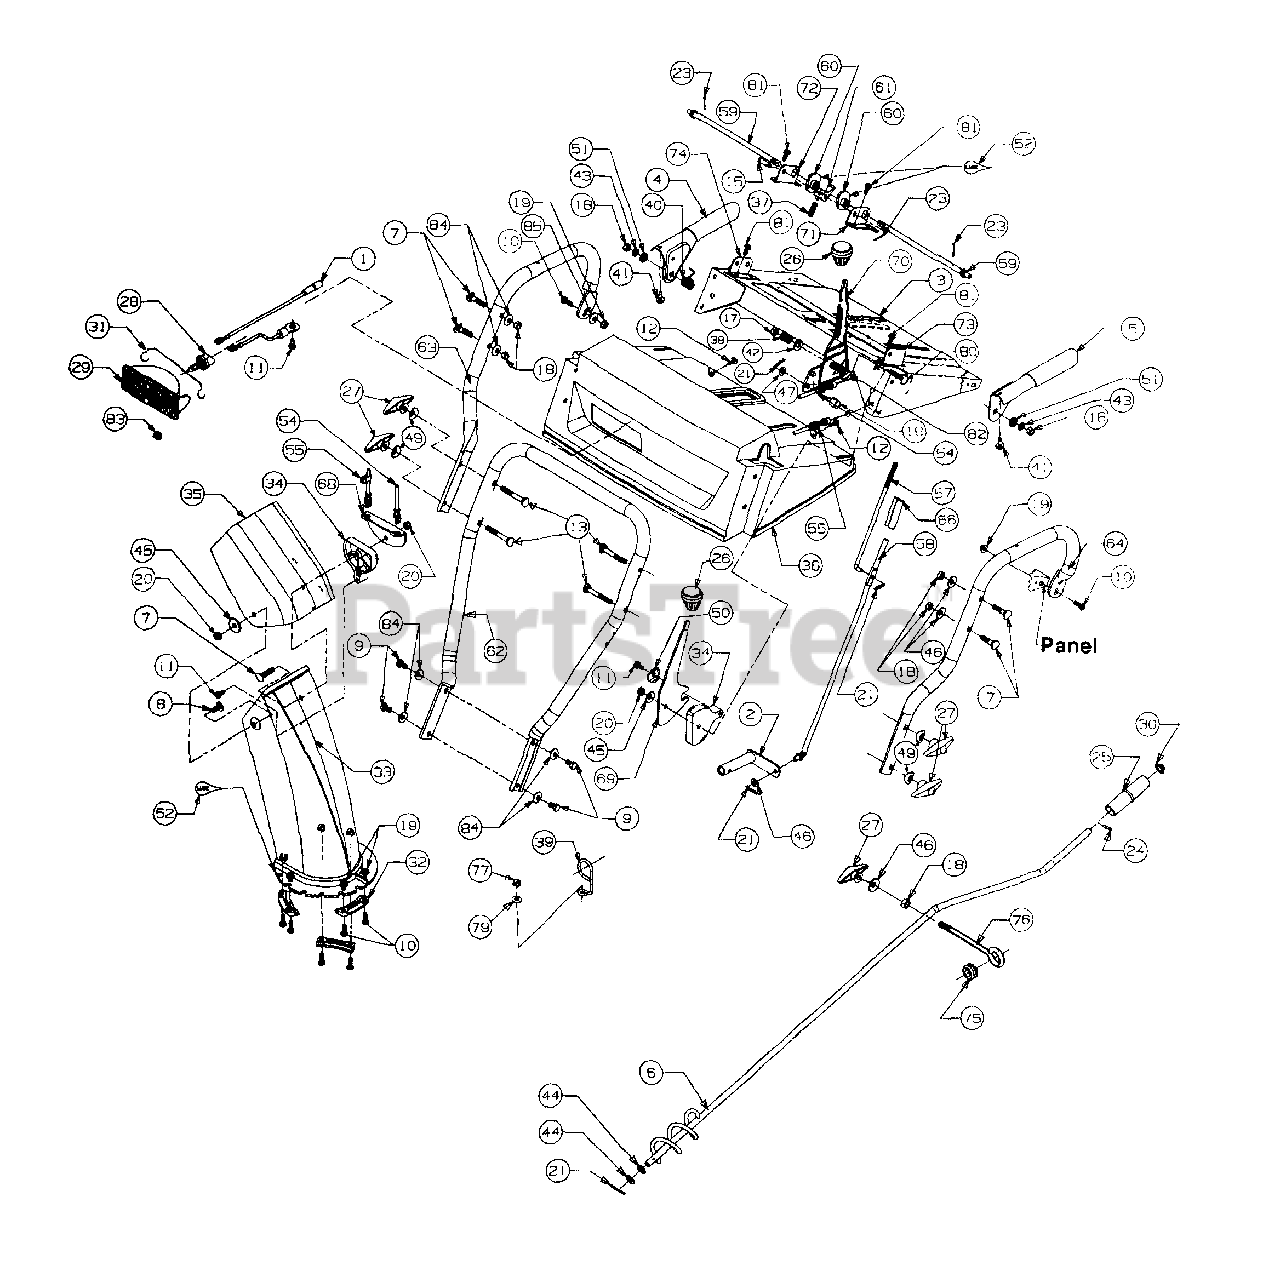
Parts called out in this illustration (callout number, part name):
1	Harness-Light
2	Arm-Shift
4	Handle-Engagement - R.H.
5	Handle-Engagement - L.H.
6	Crank-Chute
7	Bolt-Carriage
8	Bolt-Carriage
9	Screw-Hex
10	Screw-Hex
11	Screw-Washer Head-Hex
12	Screw-Hex
13	Bolt-Carriage
15	Pin-Clevis
16	Ferrule
17	Nut-Hex Lock
18	Nut-Hex
19	Nut-Hex Lock
20	Nut-Hex Lock
21	Pin-Cotter Internal
23	Pin-Cotter
24	Pin-Roll
25	Knob-Chute Crank
26	Knob-Shift
27	Knob-Wing Nut
29	Housing-Lamp
30	Cap-Push
31	Clip-Retaining
32	Keeper-Chute
33	Chute-Lower
34	Guide-Cable
35	Chute-Upper
36	Panel-Handle
37	Spring
38	Spring
39	Wire-Control
40	Spring
41	Bumper
42	Washer-Bell
43	Washer-Lock
44	Washer-Flat
45	Washer
46	Washer-Bell
47	Washer-Flat
49	Washer-Saddle
50	Washer
51	Washer
52	Lubricant
54	Cable-Chute Control
55	Cable-Chute Control
57	Rod-Shift Upper
58	Rod-Shift Lower
59	Rod-Cam
60	Cam-Handle Lock
61	Pawl-Handle Lock
63	Handle - R.H.
64	Handle - L.H.
66	Connector
69	Handle-Chute Tilt
70	Handle-Shift
71	Bracket-Handle Support - L.H.
72	Bracket-Handle Support - R.H.
74	Bracket-Handle Support - R.H.
75	Grommet Rubber
76	Eyebolt-Chute
77	Nut-Hex Lock
79	Washer-Flat
80	Screw-Hex
81	Screw-Tap Hex
82	Screw-Hex
83	Nut-Sems Hex
84	Washer-Bell
85	Washer-Bell
